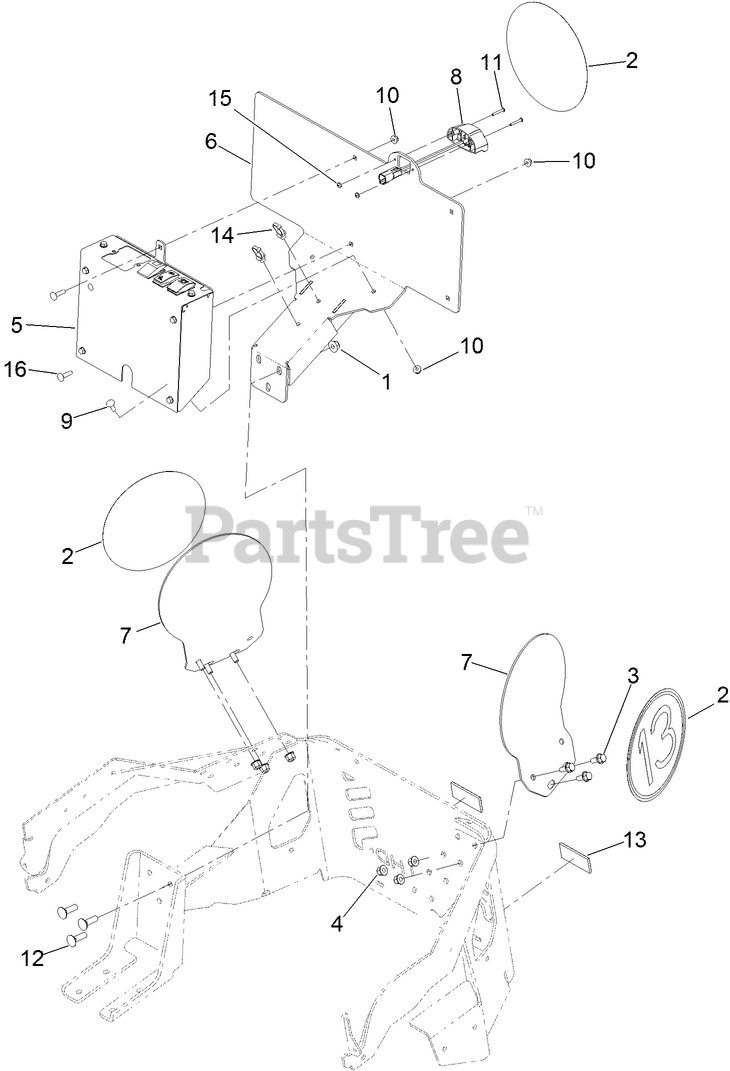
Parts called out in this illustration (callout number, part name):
1	NUT-HF, NI
2	SIGN-PVC (VINYL ADHESIVE)
3	SCREW-HHF
4	NUT-FLANGE, NI
5	CONTROL-LIGHTS, ASM
6	LICENSE-PLATE MOUNT ASM [BLACK]
7	PLATE, SPEED DECAL
8	LIGHT-PLATE, LICENSE (ECE)
9	BOLT-CARR
10	NUT-HF
11	SCREW-PPH
12	BOLT-CARR
13	REFLECTOR-ADHESIVE
14	CLIP-TIE
15	NUT-LOCK
16	BOLT-CARRIAGE
99	DECAL-SPEED, 10 KPH
